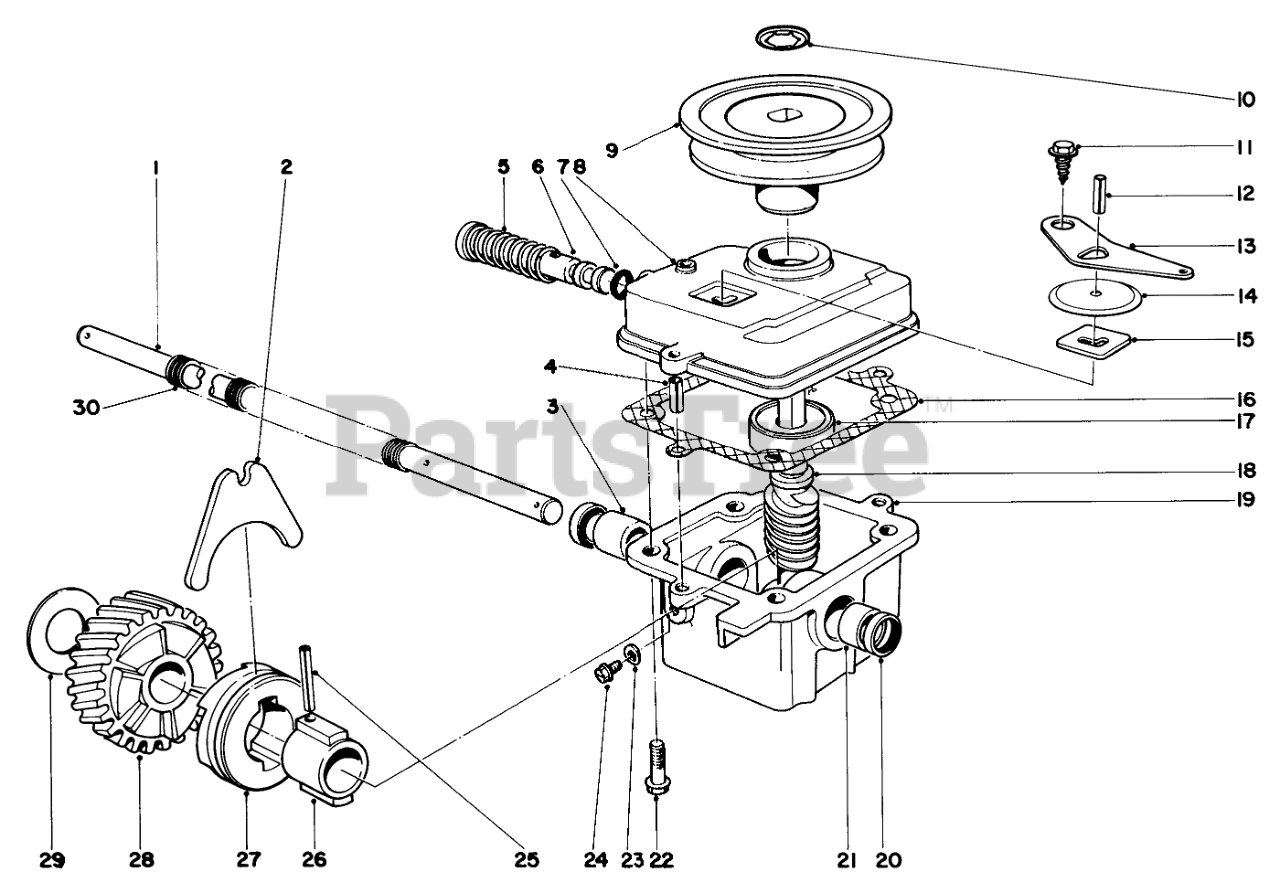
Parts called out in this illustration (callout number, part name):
1	DRIVE SHAFT (SERVCE)
2	SHIFTER FORK
3	BUSHING
4	3/16 X 1/2 ROLL PIN
5	SPRING
6	SHIFTER ROD
7	O-RING
8	Case-Upper
9	PULLEY
10	PUSH-ON 93-3236
11	Screw
12	PIN-ROLL
13	SHIFTER ARM
14	TRANS DUST COVER
15	LATCH PLATE
16	GASKET
17	Bearing
18	Worm Shaft/Gear (Incl. Ref. #28)
19	Gear Case (Incl. Ref. #3, 20 & 21)
20	Seal
21	BUSHING
22	Screw
23	FILL PLUG GASKET
24	NYLON SCREW
25	COIL PIN
26	SLEEVE
27	CLUTCH JAW
28	Helical Gear
29	THRUST WASHER
30	DRIVE SHAFT COVER
